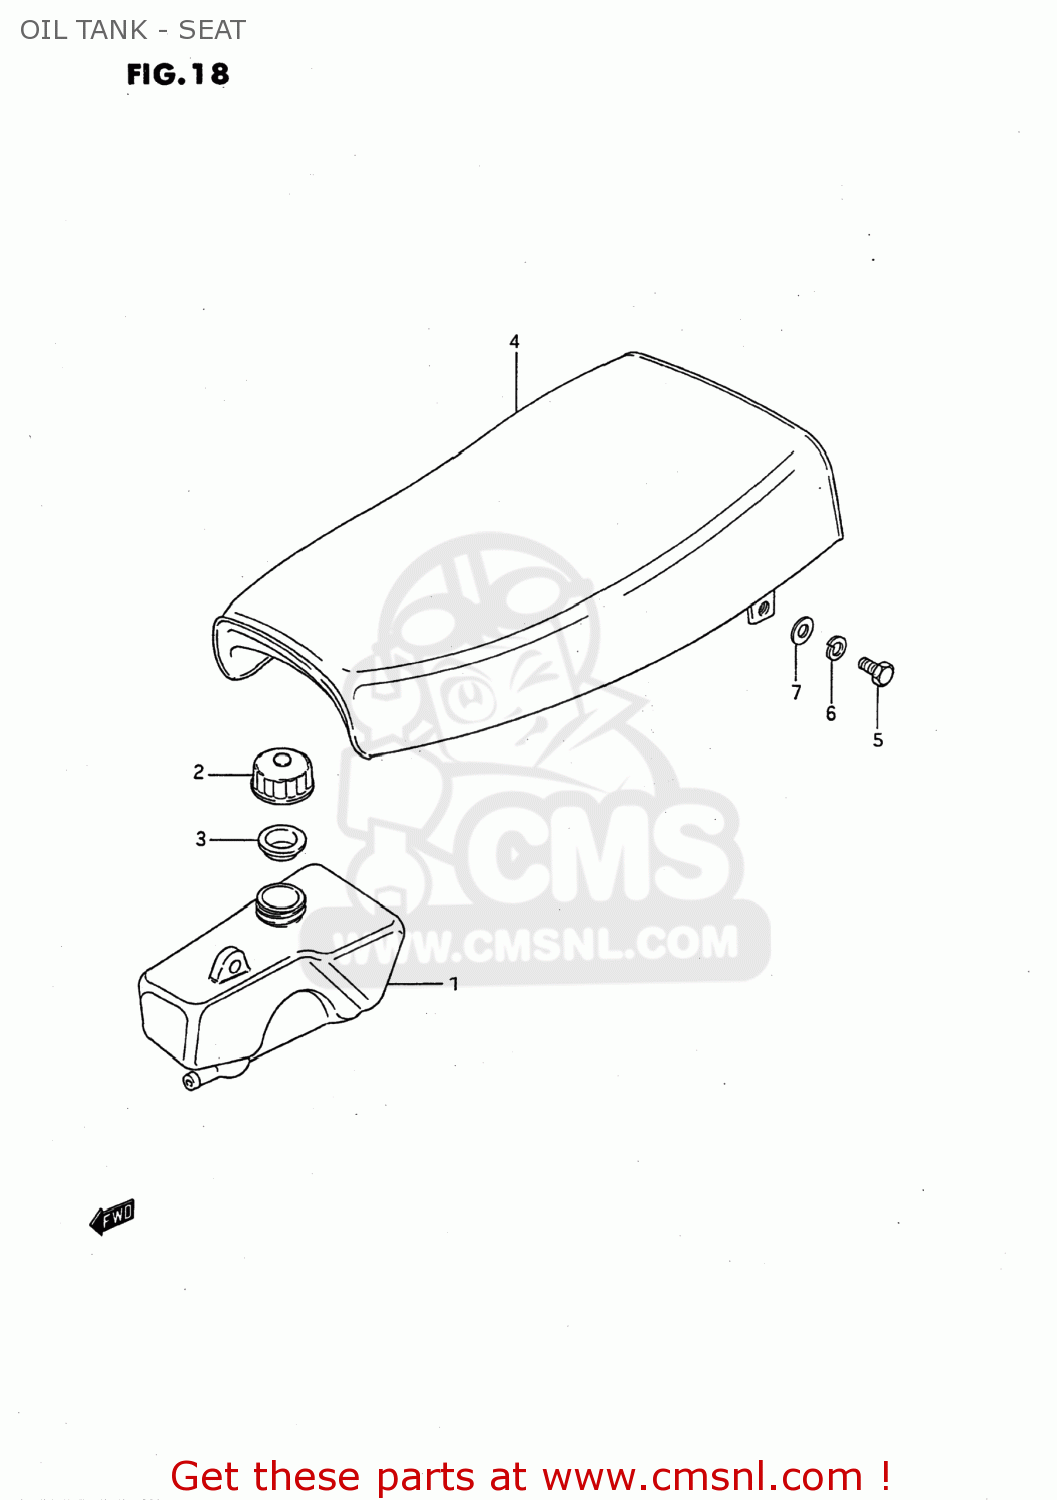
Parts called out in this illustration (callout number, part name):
1	TANK,OIL
2	CAP,OIL TANK FILLER
3	GASKET,OIL TANK (NAS)
4	SEAT SET
5	BOLT
6	WASHER,LOCK
7	WASHER
